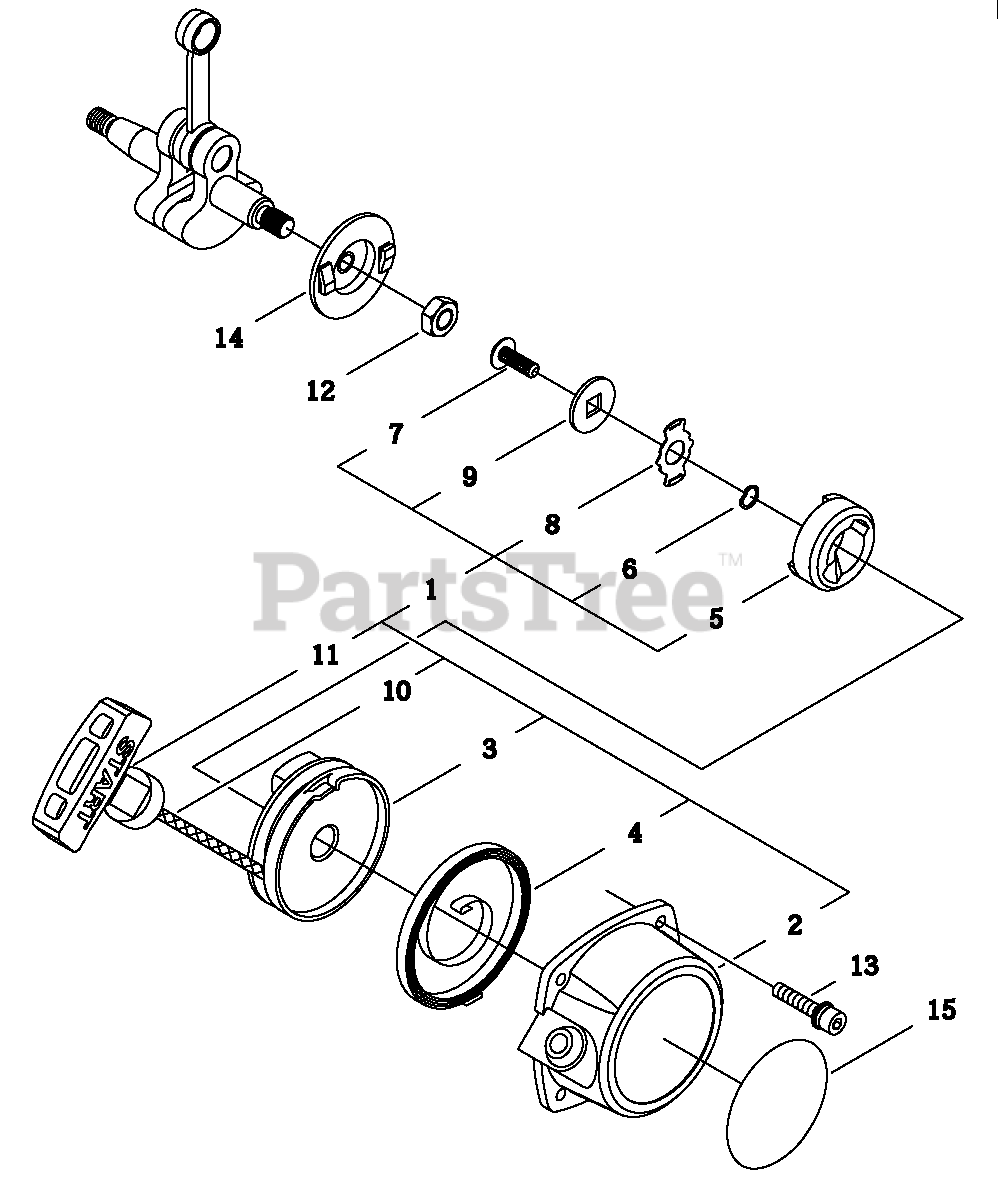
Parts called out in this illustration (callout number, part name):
1	STARTER ASSY
2	CASE, STARTER
3	REEL, ROPE
4	SPRING, REWIND
5	CATCHER, PAWL
6	WASHER - SPRING
7	SCREW - 5
8	RETAINER
9	WASHER - 5
10	ROPE, STARTER
11	GRIP, STARTER
12	NUT - 8
13	SCREW - 4X12
14	PAWL, STARTER
15	LABEL - IDENTIFICATION
